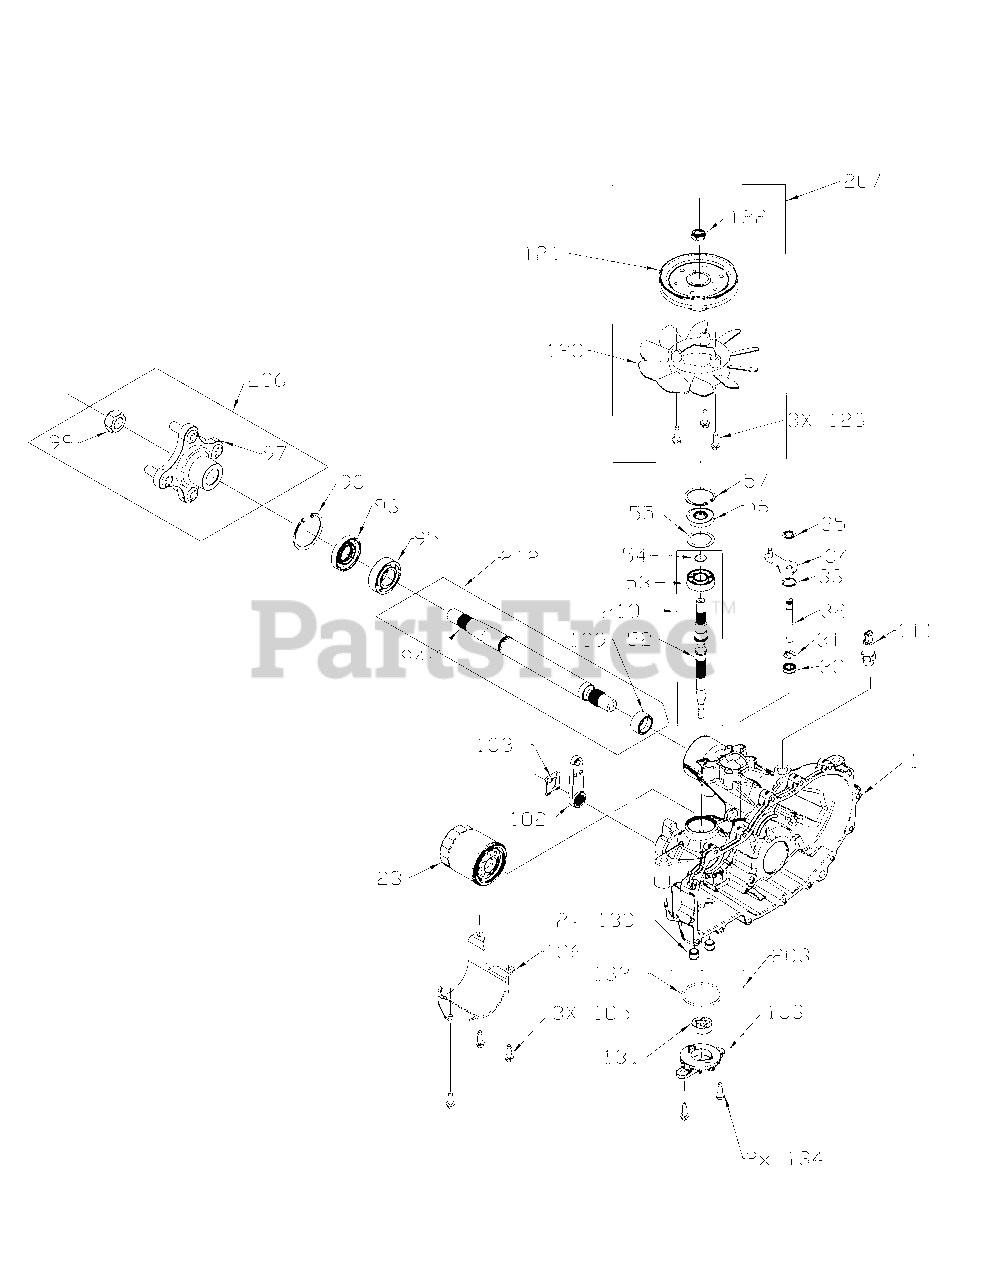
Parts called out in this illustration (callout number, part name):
1	Kit, Housing Main RH Chrg
1	Housing, Main RH Chrg
2	Kit, Cover Side RH Cntl
2	Cover, Side RH Cntl
7	HFHCS 1/4-20 x 1.25''
10	O-Ring 111.103 x .424
11	Plug 9/16/18 (Metal)
20	Center Section, RH Chrg
22	Plate, Bypass
23	Filter, Oil
24	Shock Valve
25	Shock Valve
26	Seal, Plug 1.250 x .250
27	HFHCS 3/8-16 x 1.5 (Patch)
30	Seal, Lip .375 x .75 x .25
31	Ring, Ret .375 External
32	Rod, Bypass
33	Ring, Ret .750 Internal
34	Arm, Bypass
35	Ring, Rtng .375 Ext
40	Trunnion, Swashplate
41	Seal, Lip 18 x 32 x 7
44	Control Arm RH
45	Washer .34 x .88 x .06
46	TWHCS 5/16-24 x 1.00 (Patch)
52	Shaft, Input
53	Brg, Ball 17 x 40 x 12 Open 6203
54	Ring, Ret Wire .561 ID
55	Washer 1.23 x 1.56 x .04
56	Seal, Lip 17 x 40 x 7
57	Ring, Ret 2.06 Internal
60	Bearing, Thrust
65	Bearing, Thrust Ball 30 x 52 x 13
69	Block 7 Piston Assembly
70	Washer .63 x 1.0 x .05
71	Ring, Ret 62 External
72	Gear, 16T
73	Shaft, Motor
74	Washer .72 x 1.16 x .04
80	Washer .5 x 1.0 x .03
81	Gear, 43T
82	Gear, 11T
83	Jack Shaft (Pin)
90	Ring, Ret 2.06 Internal
91	Gear, 54T
92	Spacer, .750 x 1.000 x .257
93	Bearing Ball .75 x 40 x 12
94	Shaft, Axle
95	Bearing Ball 1.0 x 52 x 15 Open 6205M
96	Seal, Lip 25 x 52 x 10 TC (Gray)
97	Hub, 4 Stud (3.56 Taper)
99	Nut, Hex Lock 3/4-16
100	Pawl, Brake
101	Shaft, Brake
102	Handle, Brake
103	Clip, Retaining
105	HFHCS 1/4-20 x .75
106	Guard, Filter - RH
111	Fitting, Str 9/16-18 SAE .5 Barb
120	Fan, 7'', 10 Blade
121	Pulley 4.5 Inch
122	Nut, Hex Lock 1/2-20 Nylon
123	HFHCS 1/4-20 x .75
130	Tube, Connecting
131	Gerotor Assembly (1.6 cc/rev)
132	O-Ring, -137, 0.103 x 2.050
133	Cover, Charge Pump
134	HFHCS 1/4-20 x .75
140	Spacer, .320 x 1.005 x .179
141	Arm, Neutral Right
142	SHCS 5/16-24 x 1 (Patch)
145	Assembly, RTN
146	Washer, .343 x 1.500 x .062
147	Spring, Extension .57 x 2''
148	Bracket Damper
200	Kit, Seal
201	Kit, Center Section, RH Chrg
202	Kit, Chrg Relief
203	Kit, Charge
206	Kit, Hub 4 Bolt
207	Kit, Fan/ Pulley
209	Hub Puller, 4 Bolt
210	Kit, Input Shaft
211	Kit, RTN Bidirectional RH
212	Kit, Axle Shaft, 13-Inch
212	Kit, Axle Shaft, 15-Inch
